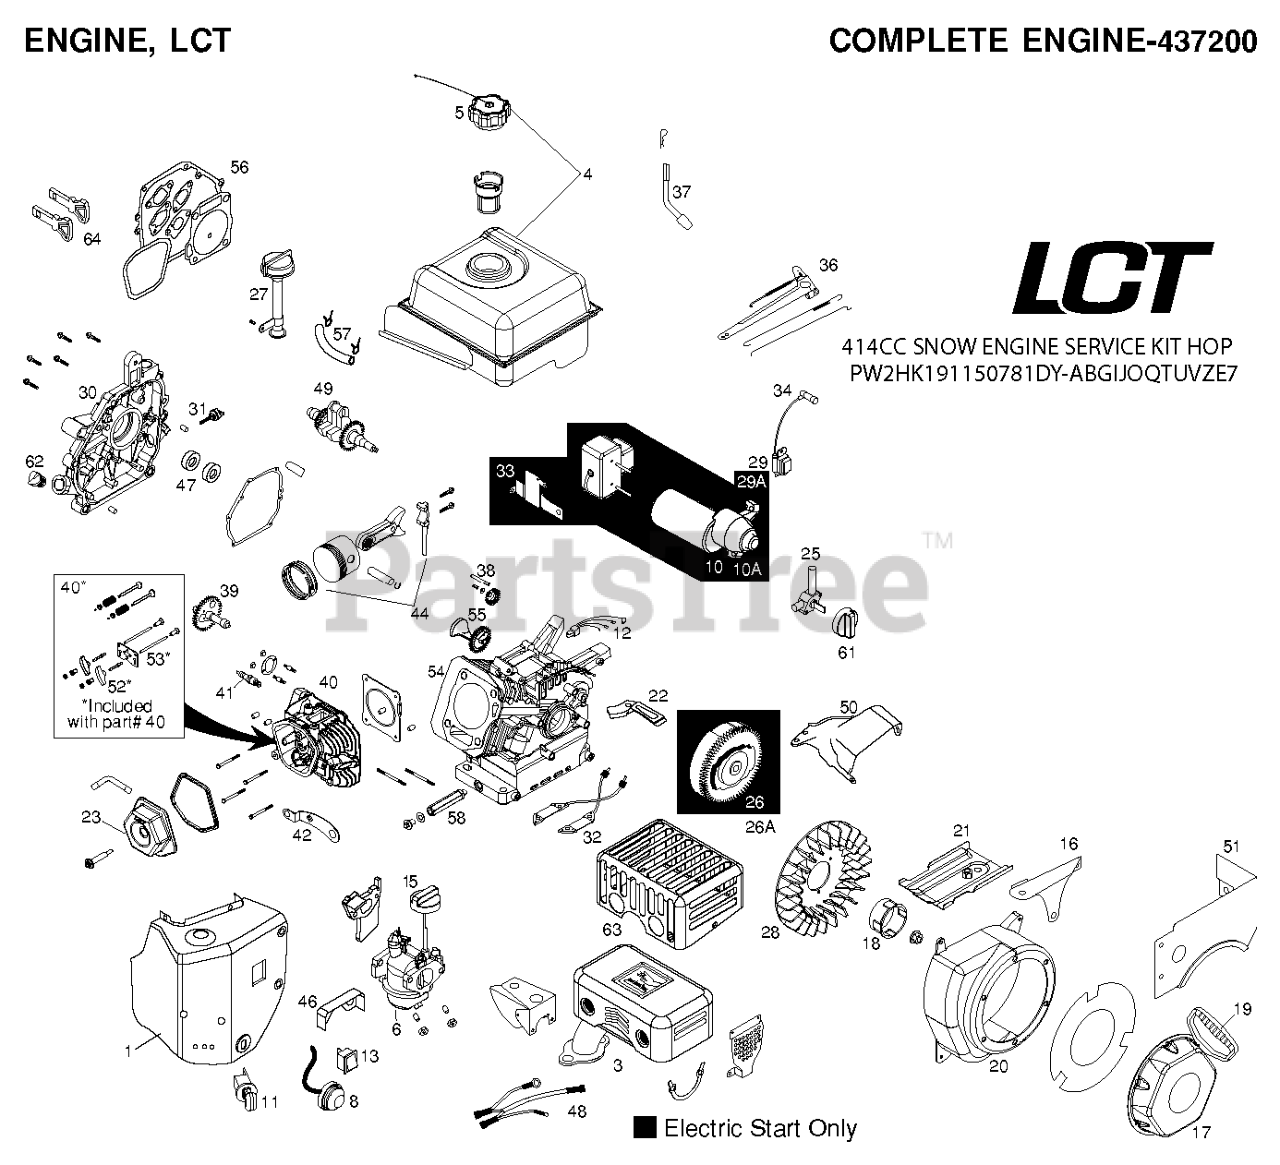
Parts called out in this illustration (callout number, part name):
1	HEATER.BOX.ASSY-SNW(SKSN4100)
3	MUFFLER.ASSY.SNOW(SKSN4200)
4	FUEL.TANK.ASSY.SNOW(SKSN4300)
5	FUEL.TANK.CAP.SNOW(SKSN4301)
6	CARBURETOR.ASSY.SNOW(SKSN4302)
8	PRIMER.BULB.ASSY(SKSN4304)
10	ELEC.START.ASSY.SNOW(SKSN4400)
10A	STARTER EUROPEAN 230V ELECTRIC
11	KEY.SWITCH.ASSY.SNOW(SKSN4401)
12	CDI.BOX.ASSY.SNOW(SKSN4404)
13	ON/OFF.SWITCH.SNOW(SKSN4403)
15	CHOKE.KNOW.SNOW(SKSN4500)
16	PLATE.GOVERN.LINK.S
17	RECOIL.START.ASSY.SNW(SKSN4600
18	STARTER.CUP.SML.SNOW(SKSN4601)
19	STARTER.GRIP.SNOW(SKSN4603.1)
20	BLOWER.HSG.ASSY.ELEC(SKSN4602
21	SHIELD.CYLINDER.SNOW(SK4141010
22	SHIELD.U/FYWHL.CHARG(SKSN4604)
23	VALVE.COVER.LCT.414CC.
25	FUEL.PETCOCK.SNOW(SKSN4900)
26	FLYWHEEL.ASSY.ELEC.START
26A	FLYWHEEL.ASSY.MAN.START
27	HIGHOIL.FILL.ASSY.KIT(SKSN4911
28	FLYWHEEL.FAN(SK4144000)
29	IGNITION COIL ASSY
29A	IGNITION.COIL.(CDI).291-414CC
30	CRANKCASE.CVR.ASSY(SK4143600)
31	DIPSTK.OIL.BLK.LCTSK4143711.1
32	CHARGING.COIL.AC/DC(SK4141710)
33	ELECTRIC.START.BRKT(SKSN4405)
34	SPARK.PLUG.BOOT.SNW,SKSN4691.1
36	GOVERNOR.ARM.ASSY(SKSN4502)
37	GOVERNOR.SHAFT(SK4143100)
38	GOVERNOR.GEAR.ASSY(SK4142900)
39	CAMSHAFT(SK4141600)
40	CYL.HEAD.ASSY.45 DEG.NON-GEN
41	SPARK.PLUG(SK2911550)
42	CDI.BOX.BRKT.SNOW(SKSN4402)
44	PISTON.AND.ROD.ASSY(SK4141400)
46	SHIELD.VAPOR(SKSN4606)
47	OIL SEAL KIT NON-GENERATOR
48	WIRE.HARNESS(SKSN4406)
49	CRANKSHAFT.KEYED
50	RP TOP SHIELD
51	SKIRT FUEL TANK
52	ROCKER ARM KIT
53	PUSH ROD TAPPET KIT
54	CYLINDER ASSY
55	COUNTER WEIGHT KIT
56	KIT.ENGINE GASKET.LCT.414CC
57	FUEL HOSE KIT
58	EXTENDED OIL DRAIN TUBE
61	FUEL KNOB-SNOW
62	NONREMVABLE.OIL.PLUG(SK4143715
63	CE COMPLIANT MUFFLER SHEILD
64	KEY SET(2 KEYS) SKSN0407.1
